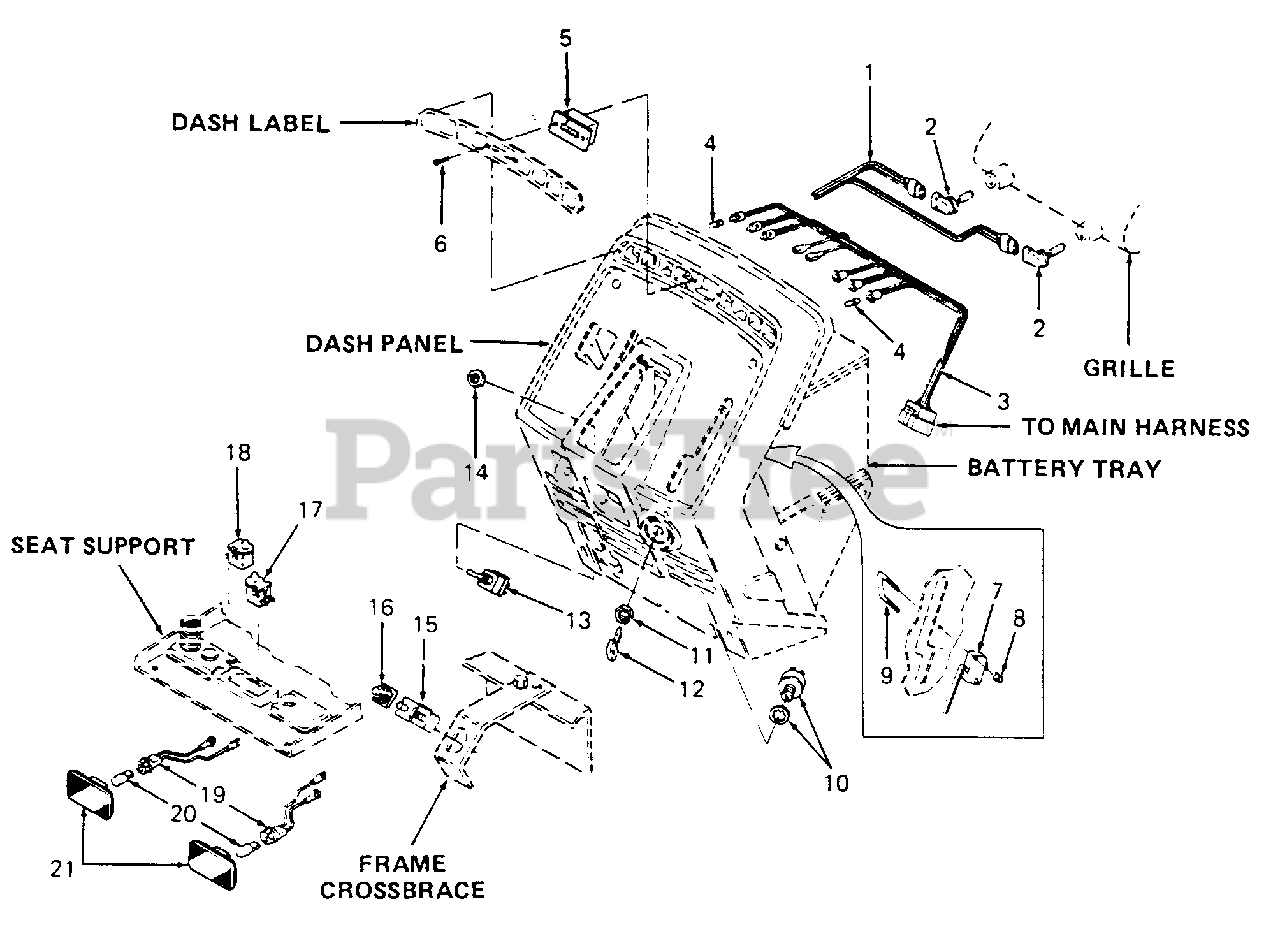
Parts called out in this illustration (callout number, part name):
1	Harness, Main Wire
2	Bulb, Head Lamp
3	Harness, Indicator Wire
4	Bulb, Indicator
5	Hour Meter
6	Screw, Truss Hd Tapp, #6 X .62 Lg
7	Switch, Reverse
8	Nut, Hex Insert Lock, #4-40
9	Screw, Switch
10	Switch, Ignition
11	Nut, Ignition Switch
12	Key, Ignition (Set of 2)
13	Switch, PTO
14	Nut, Hex, 1/2-27 X .100 Thk
15	Switch, Interlock
16	Boot, Switch
17	Switch, Snap Mount Normally Closed (Grey)
18	Switch, Snap Mount Normally Open (Black)
19	Cable Assy, Tail Light
20	Bulb, Tail Light
21	Lens Assy, Tail Light
